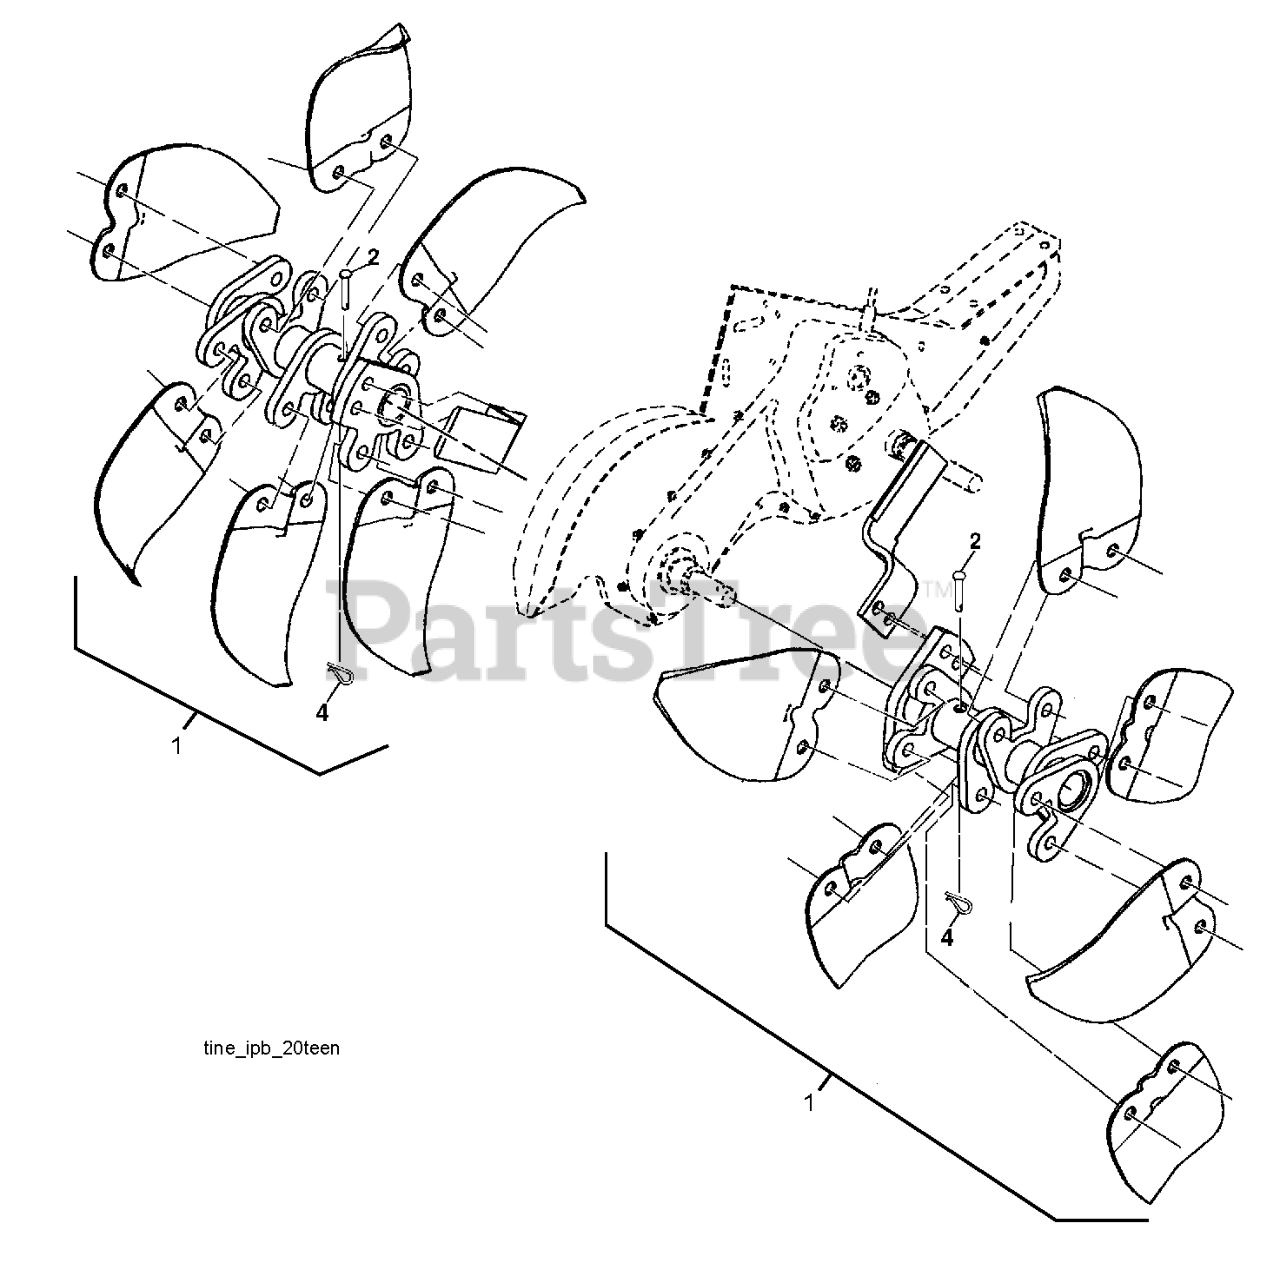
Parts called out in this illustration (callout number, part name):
1	HUB.ASM.DRT17.2004 (CMPL KIT)
2	PIN RETAINING SCREW
4	SPRING RETAINER
